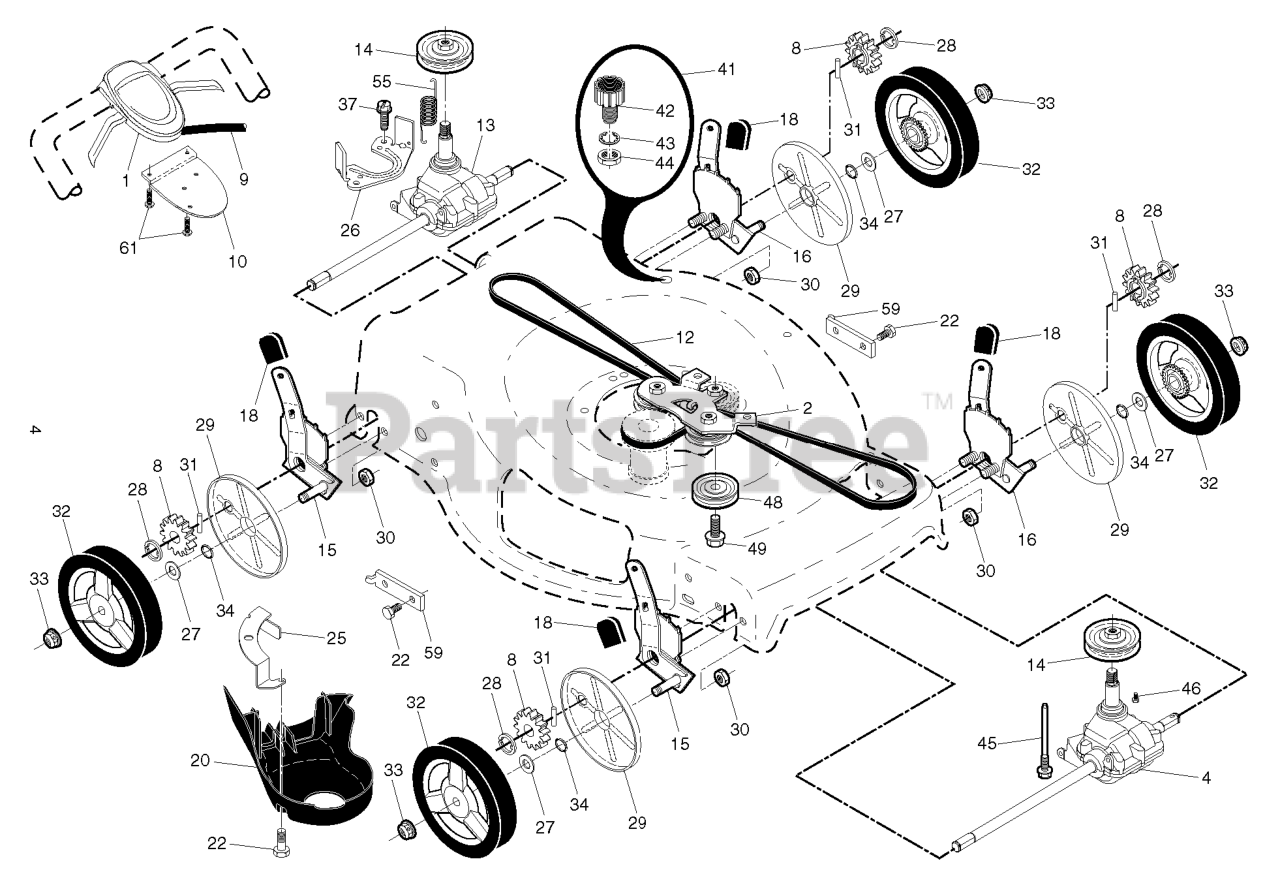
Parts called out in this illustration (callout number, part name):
1	CONTROL.AW2.22+AWD.BS.GEN SERV
2	BRACKET.ASM.AWD.BZP.BLACK
4	TRANSMISSION.22+.AWD.FRT
8	PINIION.14.TOOTH.RGD
9	CABLE.DRIVE.RWD.WALK.
10	BRACKET DUAL TRIGGER CONTROL
12	BELT.DRIVE.AWD.13 ZINC DUSTED
13	TRANSMISSION.22+AWD.WALK.MOWER
14	PULLEY.DRIVE.SM.AWD/RWD
15	ADJUSTER.ASM.22+FGD.RF /AWD RT
16	ADJUSTER.ASM.22+FGD.LF /AWD LT
18	SELECTOR KNOB
20	COVER.REAR.DRIVE.22+2013
22	BOLT.5/16HEX.WHS.HD
25	BRACKET.DRIVE.COVER.RGD.BZP
26	BRACKET.TRAN.BELTKEEPER.22+RGD
27	WASHER FLUT
28	E-RING 7/16 RE
29	COVER.DUST.WHEEL.INNER.WALK
30	NUT.FLANGE.1-4-20-SERR
31	PAWL, DRIVE
32	WHEEL.8".AWD.3SP.EXT.DR.GREY
33	NUT.HEX.FLANGE.3/8-16.LO(3 2)
34	O-RING..070X.487.NEOPRENE
41	KIT.WASH-OUT.PORT
42	FITTING, HOSE, WATER WASHOUT
43	WASHER.LOCK.INTERNAL.TOOTH
44	LOCKNUT.HEX.WITH.O-RING
45	SCREW.HI-LO.5/16-14 X 4.10
46	SCREW.HI-LO. 5/16 X 1.00
48	PULLEY.ASM.22+ AWD
55	SPRING.RETURN.AUTO.
59	BRACKET.SUPPORT.22+RWGD.BZP
61	SCREW, PHILLIPS HEAD 10 X 5/8
